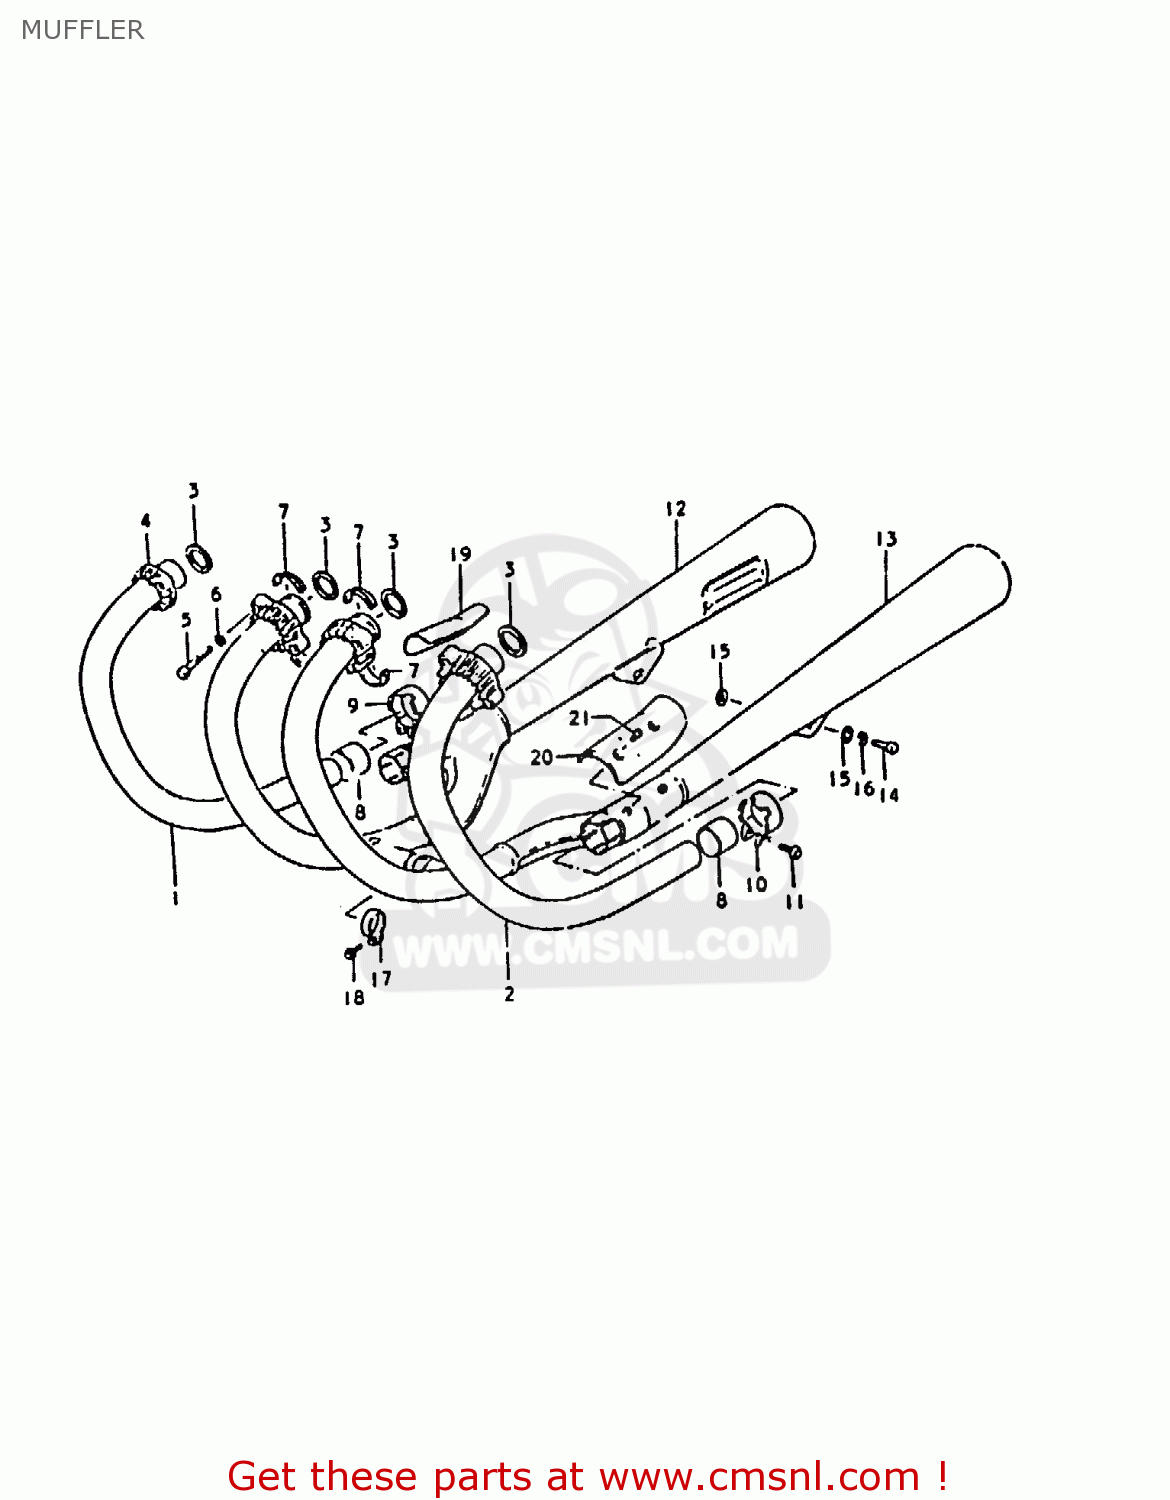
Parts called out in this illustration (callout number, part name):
1	PIPE,EXHAUST,R
2	PIPE,EXHAUST,L
3	GASKET,EXHAUST PIPE (NAS)
4	CLAMP,EXHAUST PIPE
5	BOLT
6	LOCK WASHER
7	PLATE,EXHAUST P
8	CONNECTOR,MUFFLER
9	CLAMP,MUFFLER CONNECTOR,R
10	CLAMP,MUFFLER CONNECTOR,L
11	BOLT
12	BODY,MUFFLER
13	BODY,MUFFLER
14	BOLT 10X30
15	WASHER
16	LOCK WASHER
17	CLAMP
18	BOLT
19	COVER,MUFFLER
20	COVER,MUFFLER,LEFT
21	SCREW
